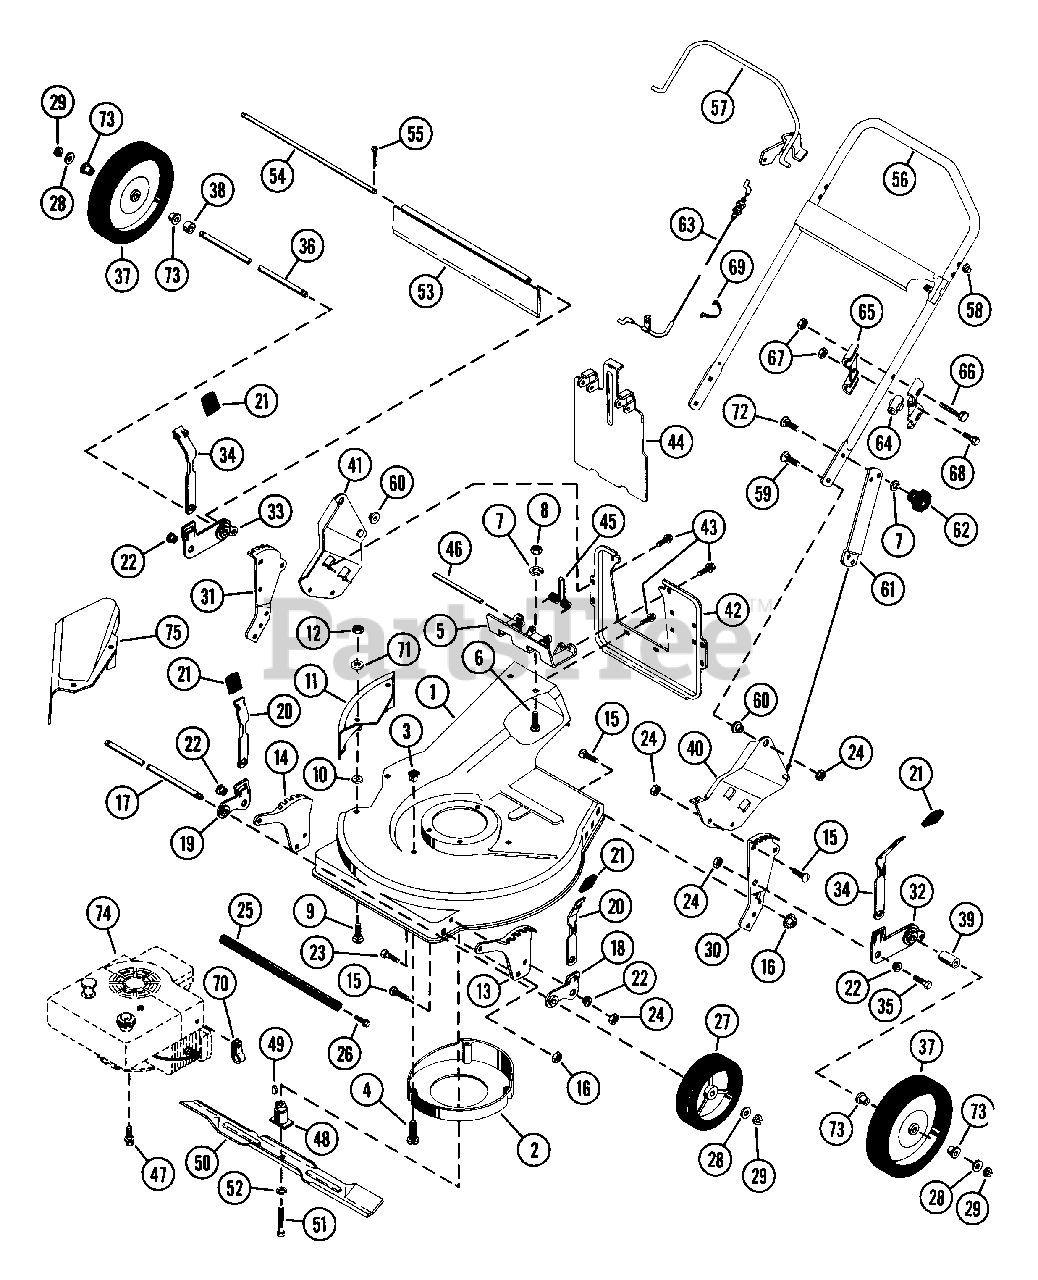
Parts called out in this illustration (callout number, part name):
1	21 INCH MOWER PAN WELDMENT
2	CENTER BAFFLE
3	PLASTIC GROMMET
4	SCR-TAP 10-16X.62 SLPH PL AB
5	HINGE PLATE
6	BLT-RDHDSQNK .312-18X.62SHTPL
7	WSHR-LK .312X.097 PL HVY
8	NUT-HEX .312-18
9	BLT-RDHDSQNK .31-18X.75 SHT PL
10	NUT-PUSH .312
11	SIDE DISCHARGE COVER
12	NUT-LK-NYL.312-18 PL
13	LEFT FRONT QUADRANT
14	RIGHT FRONT QUADRANT
15	BLT-RDHDSQNK .312-18X.62SHTPL
16	NUT-FLG. .312-18 PL
17	FRONT AXLE
18	LEFT ADJUSTOR BRACKET ASSEMBLY
19	RIGHT ADJUSTOR BRACKET ASSEMBL
20	FRONT HEIGHT ADJUSTMENT LEVER
22	BSHG-FLG .315X.500X.354X.875
23	BLT-HEX .31-18X1.00 PL GR 2
24	NUT-LK .312-18 GR A PL
26	BLT-SCRHFWH .38-16X.75 PL
27	T/WHL ASSY 7X1.50
28	WSHR-FL-STL .505X.880X.072 PL
29	RG-RTNG-EXT .438X.035
30	LEFT REAR QUADRANT
31	RIGHT REAR QUADRANT
32	REAR BRACKET AND BEARING ASSEM
33	REAR BRACKET AND BEARING ASSEM
34	HEIGHT ADJUSTMENT LEVER
35	BLT-HEX .31-18X.75 PL GR2
36	REAR AXLE-PUSH MOWER
37	WHL 10 IN O.D.
38	SPACER .75 X .51 X .50
39	SPACER .75 X .50 X 1.25
40	LH HANDLEBAR MTG BRACKET WELDM
41	RH HANDLEBAR MTG BRACKET WELDM
42	CATCHER MOUNTING PLATE
43	SCR-TAP 10-24X.375 HWH PL TR
44	DISCHARGE COVER
45	SG-TORS .090X.550X2.88
46	HINGE PIN
47	SCREW - FLG WIZ LOCK HH PL
48	BLADE ADAPTER
49	KEY-WDRF .156X.625X.25 SAE 6
50	21 INCH MOWER BLADE
51	BLT-HEX .38-24X2.00 PL GR5
52	WSHR-LK .375X.094 MED PL
53	REAR PROTECTIVE GUARD
55	PIN-COTR .06X.50
56	HANDELBAR W/DECAL
57	START BAIL - RECOIL
58	NUT-PUSH .312 DIA. PAL
59	BLT-RDHDSQNK .31-18X.75 GR5 PL
60	BSHG, FLG .325X.499X.26X.88
61	HANDLEBAR BRACKET
62	FLUTED WING
63	CABLE - ENGINE
64	PULL CORD RETAINER
65	BRACKET - ROPE GUIDE
66	BLT-HEX .25-20X1.50 PL GR5
67	NUT-LK-CTR .250-20 PL
68	BLT-HEX .25-20X.50 PL GR2
69	CABLE RETAINER
71	WSHR-FL-STL .38X.875X.083 PL
72	RVT-TBLR .187X1.218 OH ST PL
73	BSHG-FLG .500X.625X.500X.750
75	DISCHARGE CHUTE
76	BLT-RDHDSQNK .31-18X1.75 SHTPL
